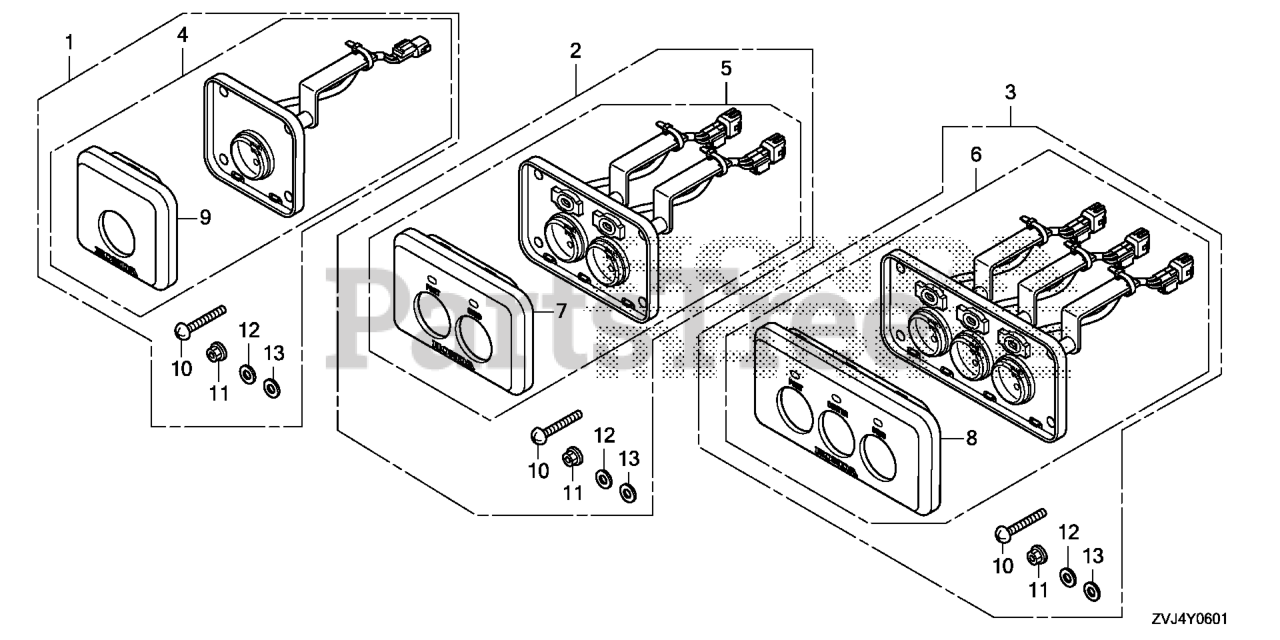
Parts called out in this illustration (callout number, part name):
1	PANEL KIT, START STOP SWITCH (ALL)
1	PANEL KIT, START STOP SWITCH (SINGLE)
1	PANEL KIT, S/S SW
2	PANEL KIT, S/S SW
3	PANEL KIT, S/S SW
4	PANEL ASSY., START STOP (ALL)
4	PANEL ASSY., START STOP (SINGLE)
5	PANEL ASSY., START STOP (TWIN)
6	PANEL ASSY., START STOP (TRIPLE)
7	PANEL, START STOP (TWIN)
8	PANEL, START STOP (TRIPLE)
9	PANEL, START STOP (ALL)
9	PANEL, START STOP (SINGLE)
10	SCREW, PAN (5X40) DUAL QTY = (8) (SINGLE)
11	NUT, FLANGE (5MM)
12	WASHER, PLAIN (5MM)
13	WASHER, SPRING (5MM)
13	WASHER, SPG (5MM)
